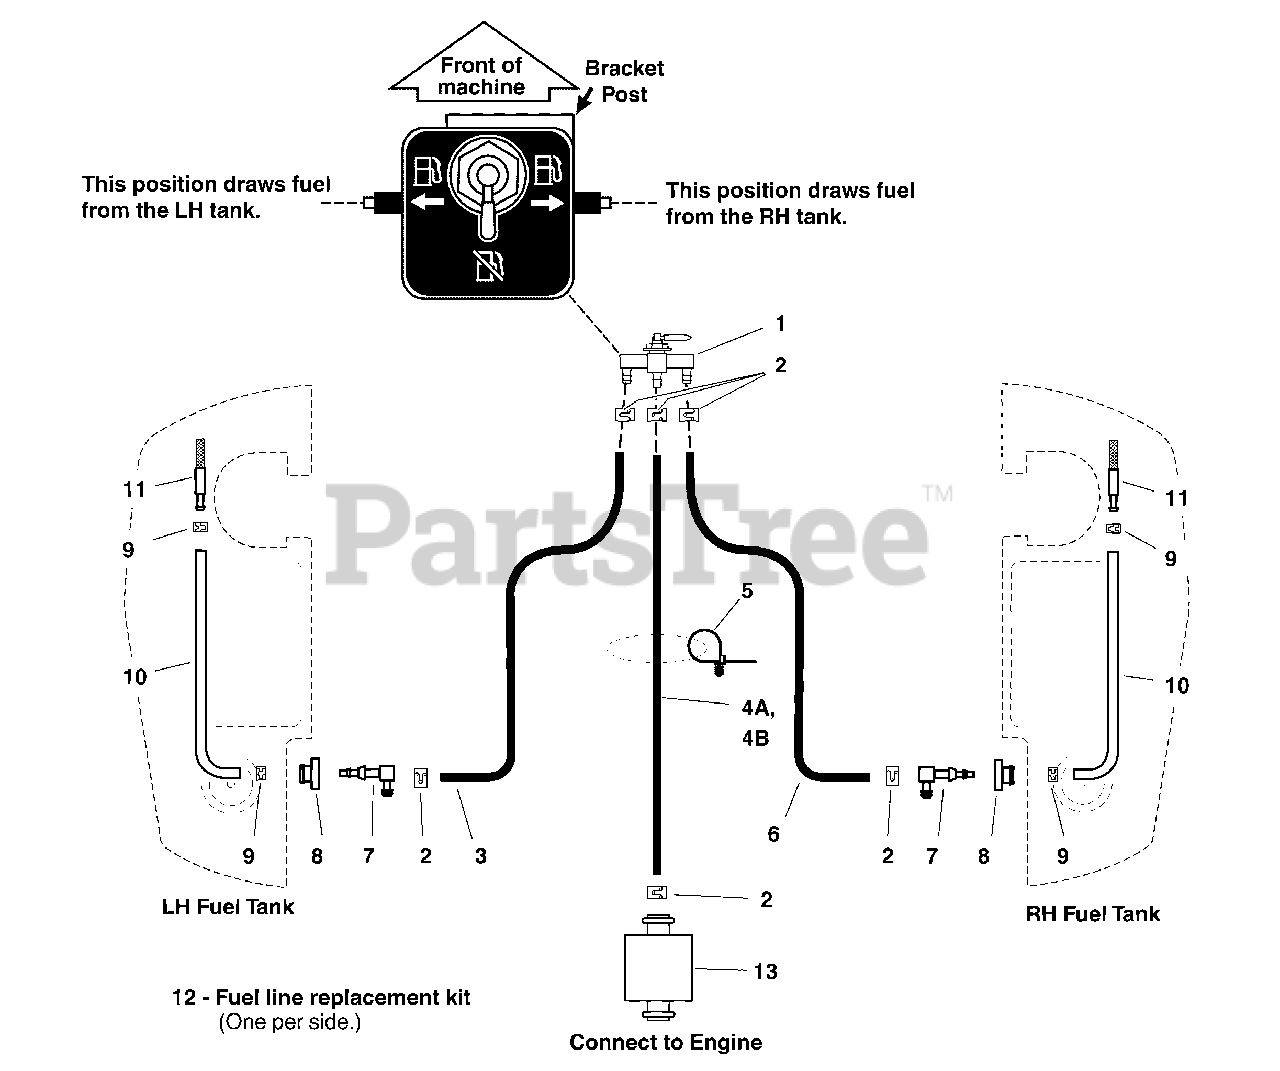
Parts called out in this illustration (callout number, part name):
1	VALVE, FUEL, STR OUTLET
2	CLAMP, HOSE EXTERNAL, 1/2 - RED
3	HOSE, 1/4" FUEL, 35.00"
5	CABLE, TIE-PUSH MOUNT
6	HOSE, 1/4" FUEL, 10.00"
10	HOSE ASSEMBLY
12	FUEL LINE REPLACEMENT KIT
13	FUEL FILTER (SV)
